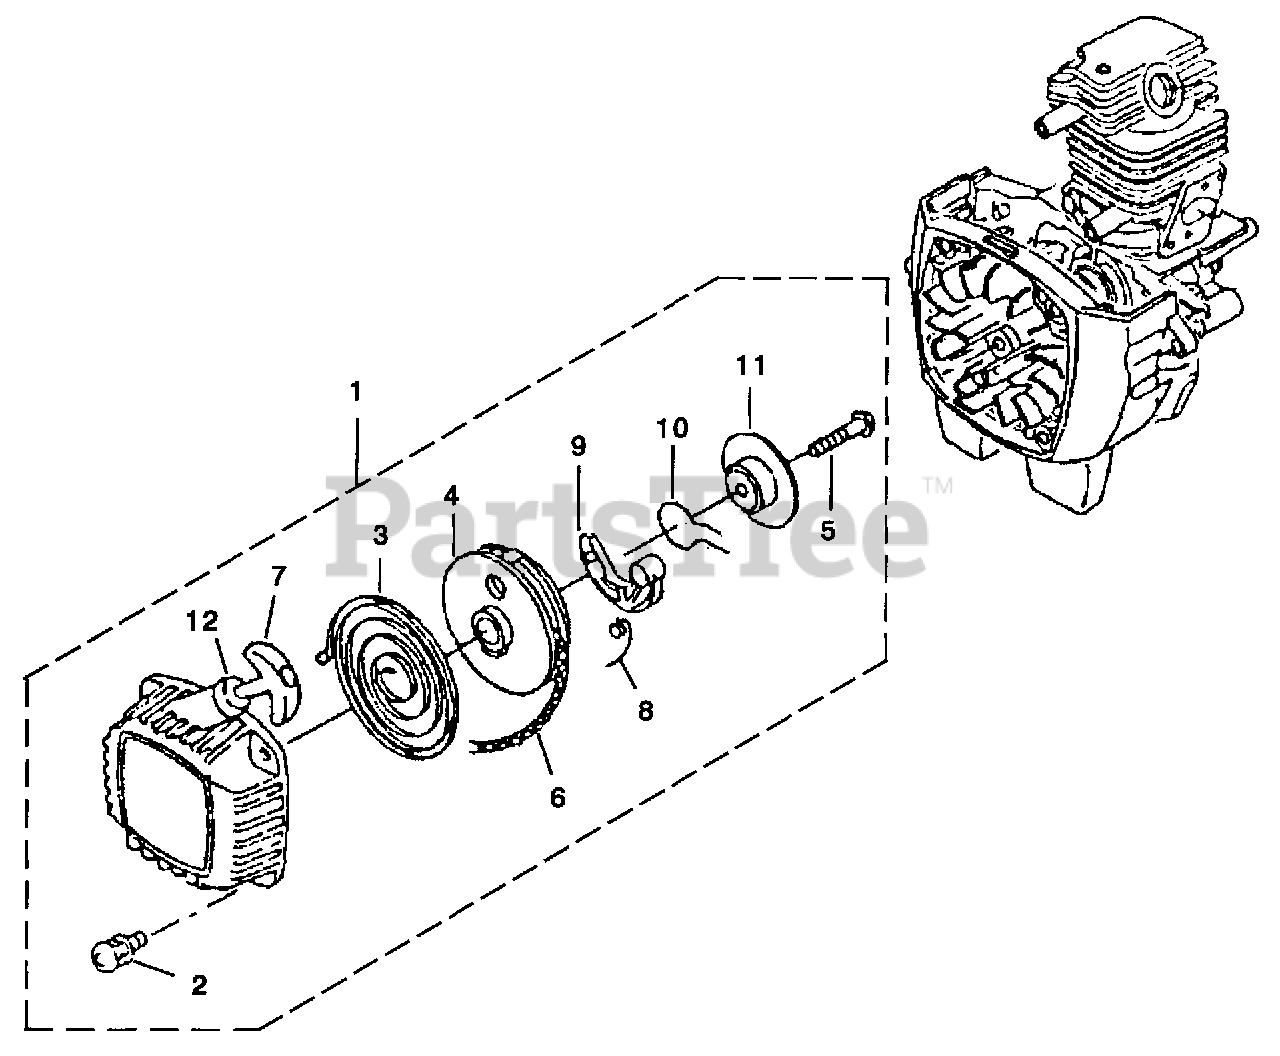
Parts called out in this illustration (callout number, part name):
1	STARTER COMPLETE
2	SCREW ASSEMBLY (M5 x 14)
5	SCREW-Set
6	ROPE-Starter
8	SPRING-Return
10	SPRING-Friction
11	PLATE-Friction
12	DAMPER-Grip
